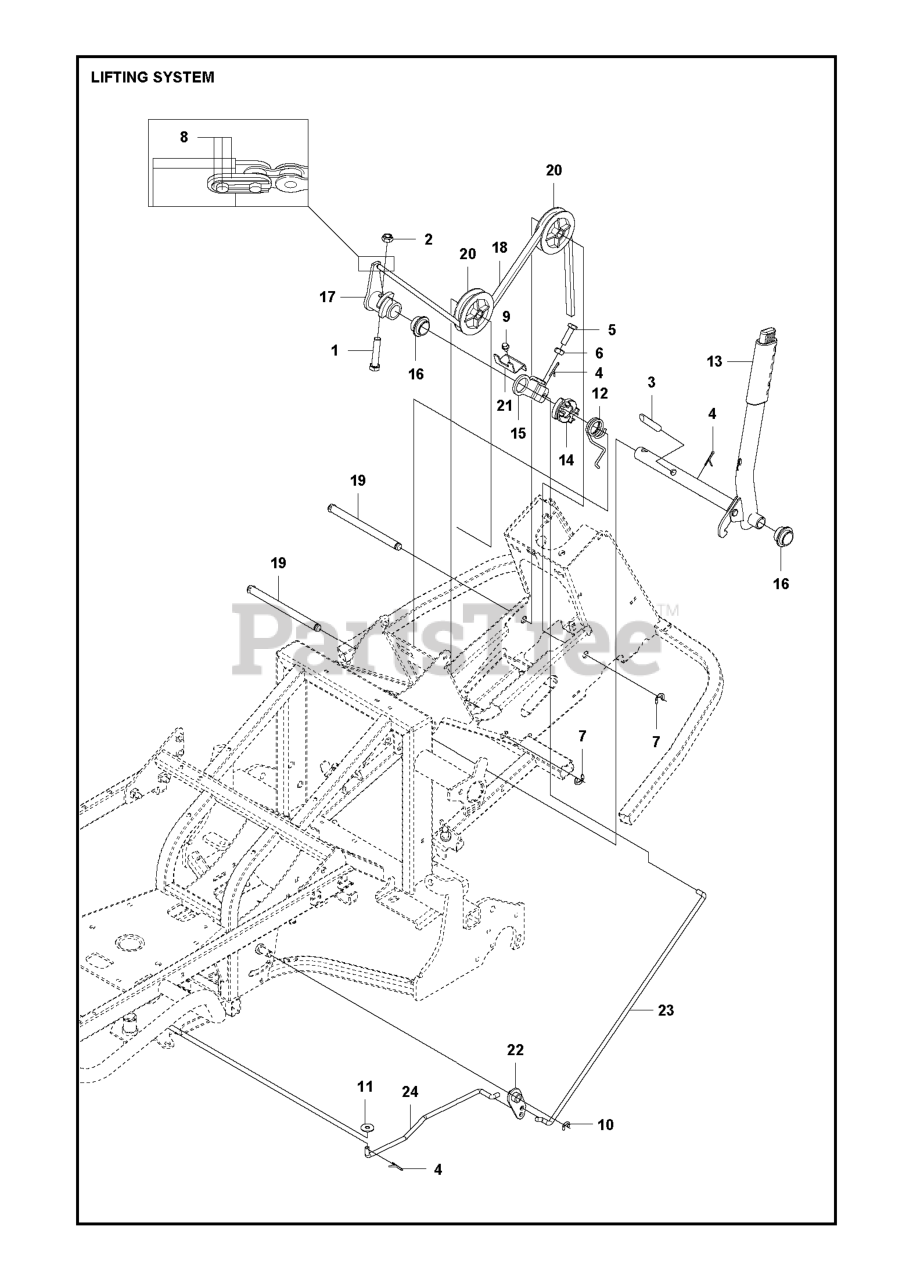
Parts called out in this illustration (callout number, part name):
6	NUT
10	RETAINING RING
15	LIFTING ARM LINK
18	ROLLER CHAIN
